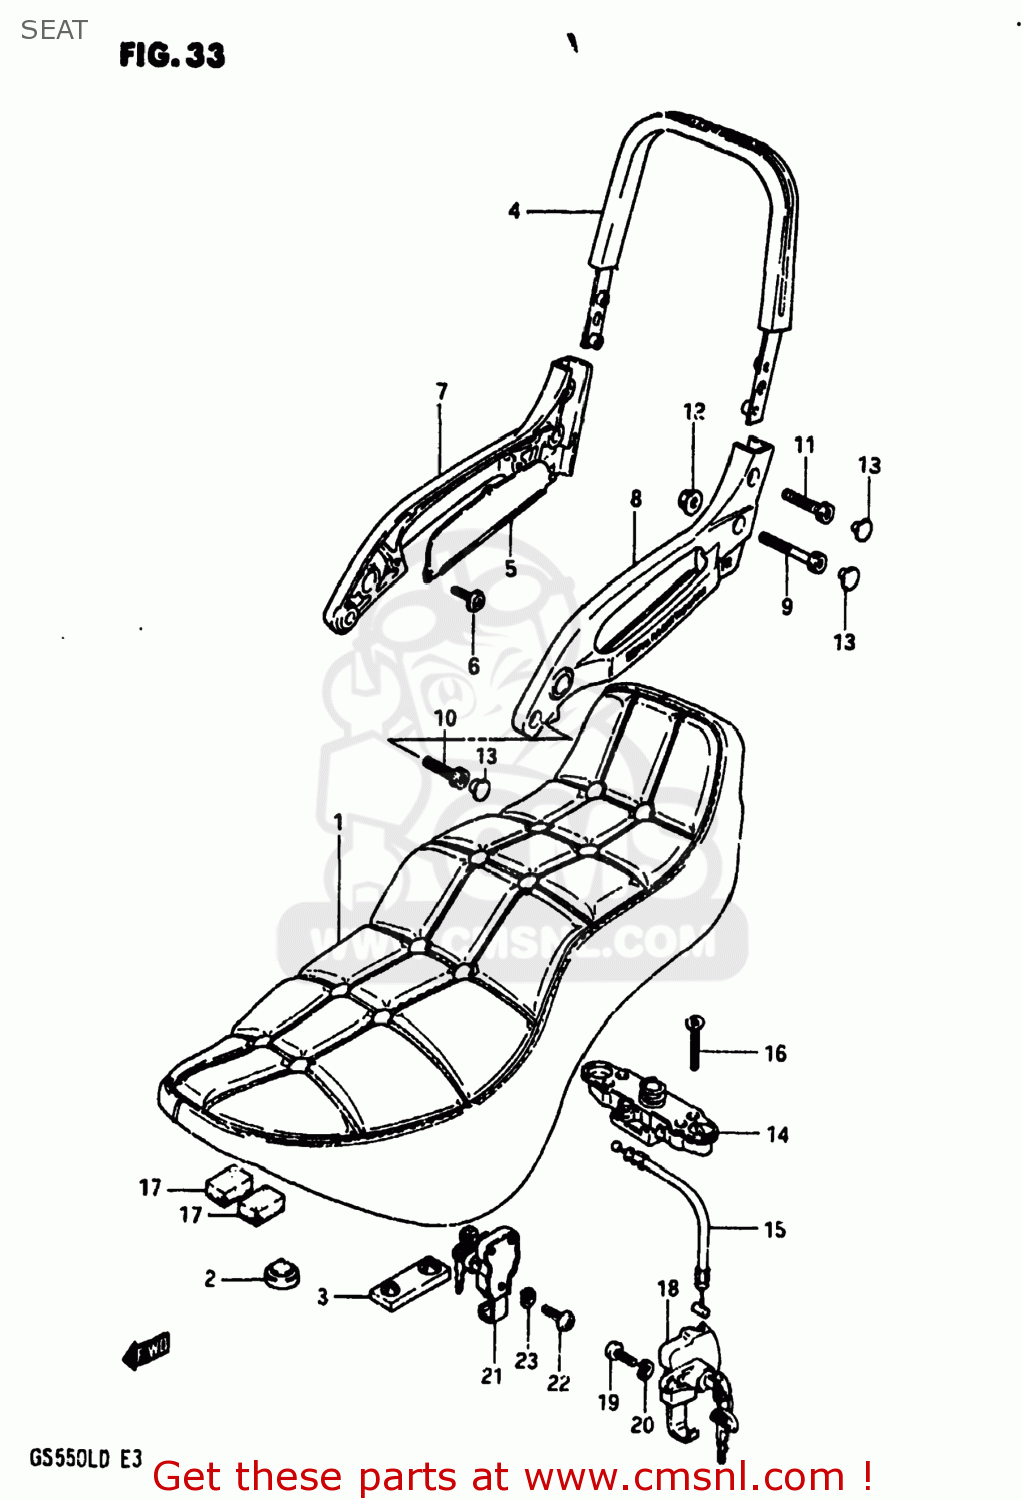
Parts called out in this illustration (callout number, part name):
1	SEAT ASSEMBLY
2	CUSHION
3	CUSHION,SEAT
4	HANDLE,PILLION RIDER
6	SCREW
7	BRACKET,PILLION RIDER
8	BRACKET,PILLION RIDER
9	BOLT
10	BOLT
11	BOLT
12	NUT
13	CAP(OD:10)
14	LOCK ASSEMBLY,SEAT STRIKER
15	CABLE,SEAT LOCK
16	SCREW
17	CUSHION,BATTERY
18	LOCK ASSEMBLY,SEAT & HELMET
19	SCREW
20	LOCK WASHER
21	LOCK ASSEMBLY,HELMET
22	SCREW
23	LOCK WASHER
